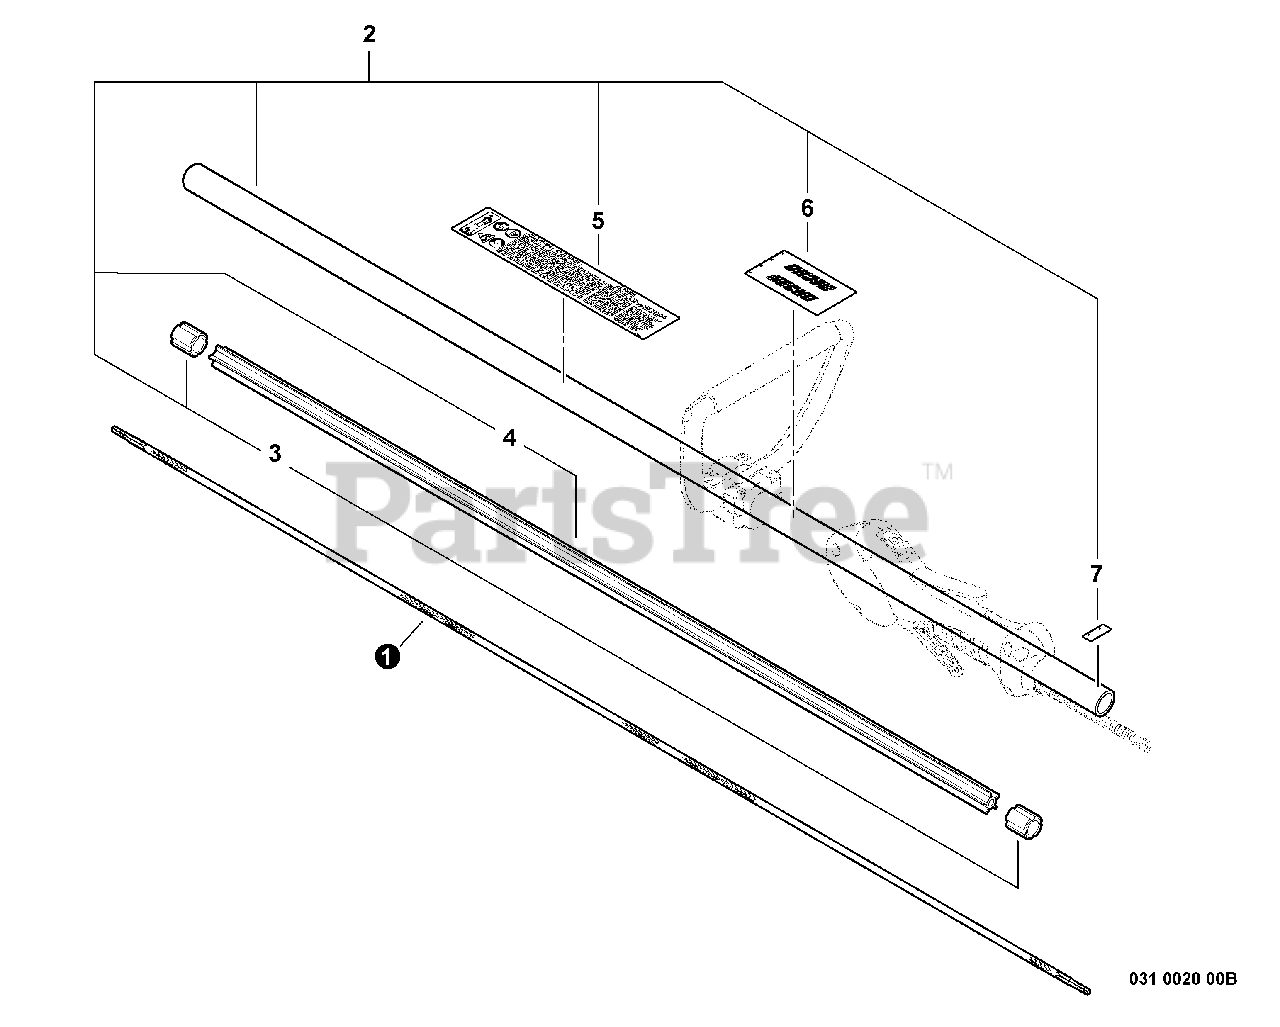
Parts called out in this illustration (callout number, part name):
1	DRIVESHAFT - FLEXIBLE L= 1522
2	MAIN PIPE ASSY
4	LINER, FLEXIBLE 21.6×1420
5	LABEL, CAUTION
6	LABEL, HANDLE LOCATION
7	LABEL - ALIGNMENT
